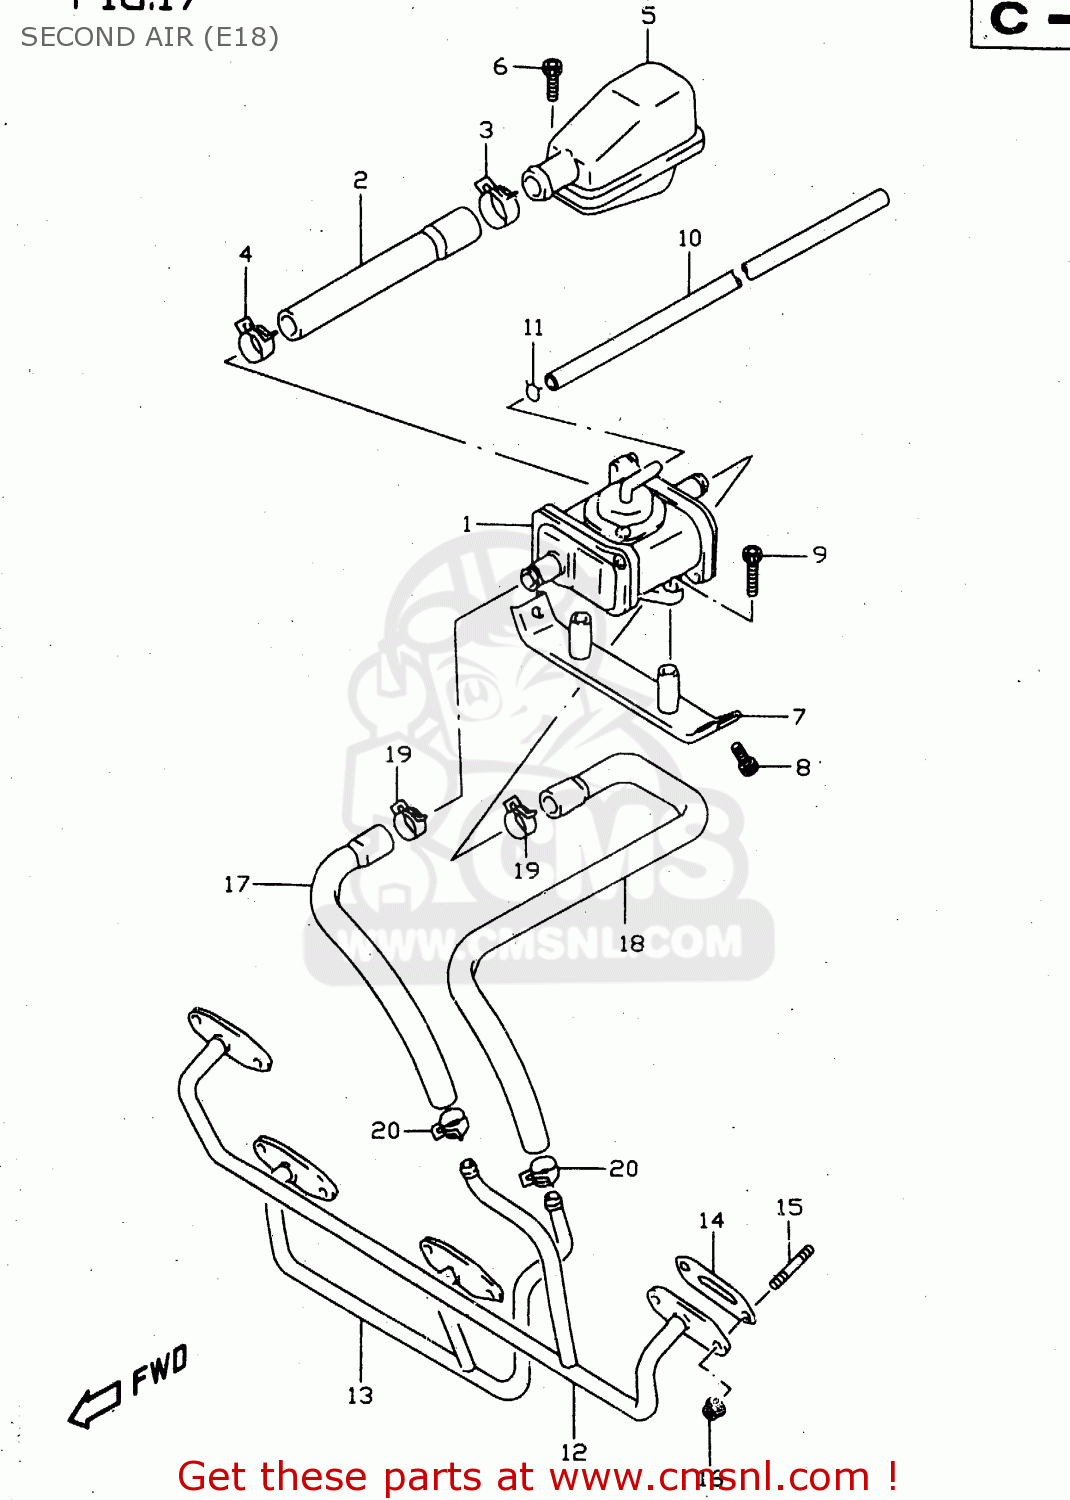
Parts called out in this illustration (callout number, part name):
1	VALVE ASSY,2ND AIR
2	HOSE, 2ND AIR CLEANER
3	CLIP
4	CLIP
5	CLEANER,2ND AIR
6	BOLT MAGNETO S
7	BRACKET,2ND AIR VALVE
8	BOLT MAGNETO S
9	BOLT,CYL.OIL P
10	HOSE(4X7X600)
11	CLIP
12	PIPE,2ND AIR OUTER
13	PIPE,2ND AIR INNER
14	GASKET,SECOND AIR PIPE (NAS)
15	STUD BOLT
16	NUT
17	HOSE,2ND AIR VALVE FR
18	HOSE, 2ND AIR VALVE REAR
19	CLIP
20	CLIP
